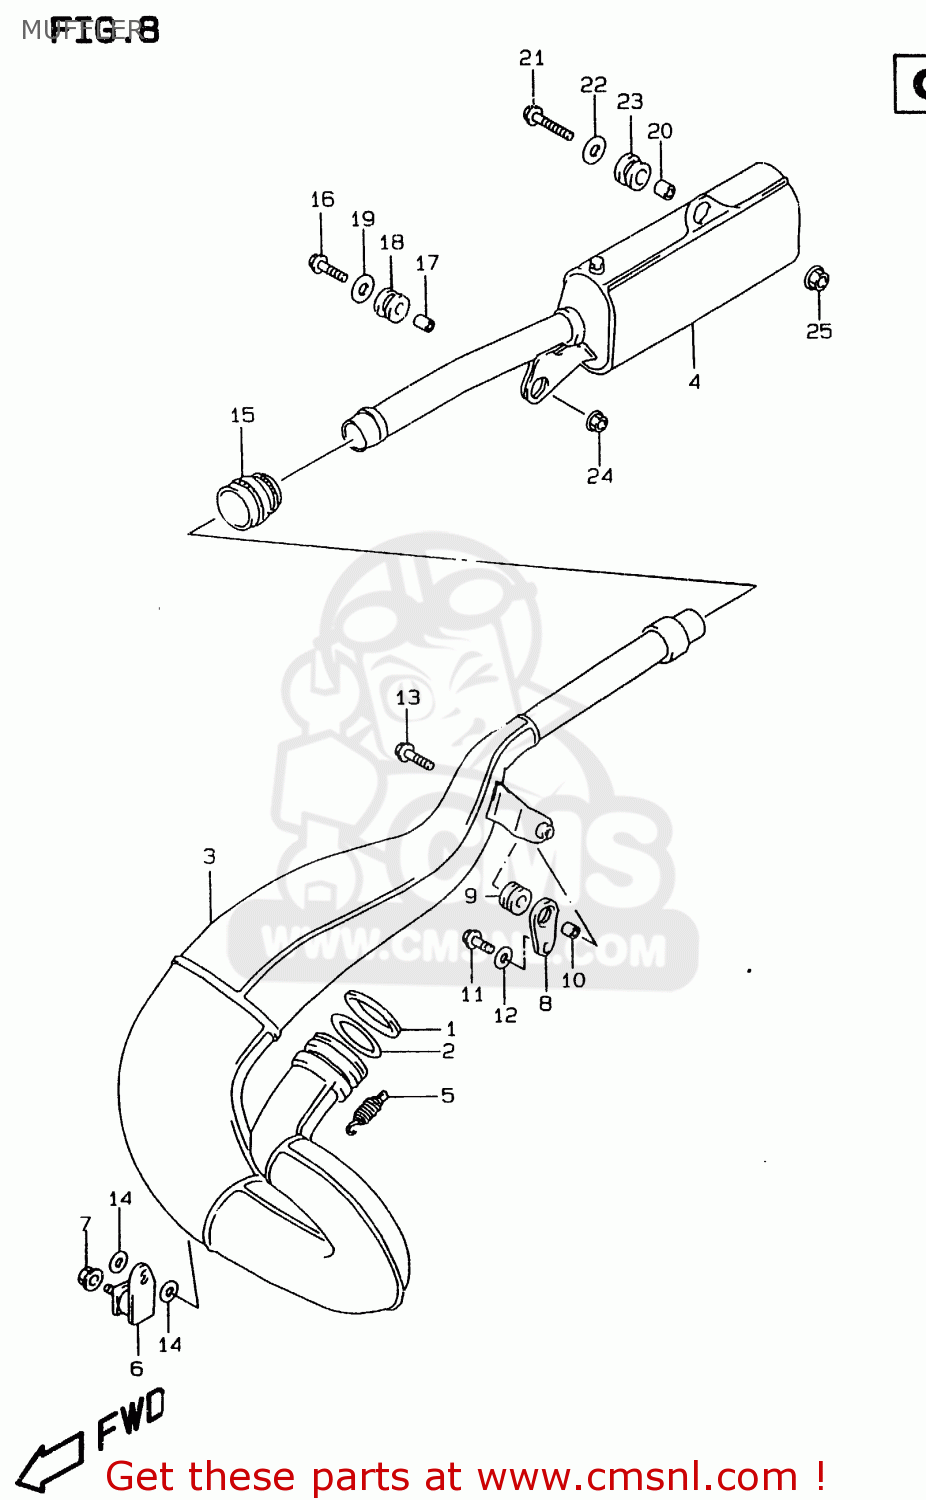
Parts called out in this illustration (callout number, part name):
1	WASHER,EXHAUST PIPE
2	O RING,EXHAUST PIPE
3	BODY,MUFFLER,FIRST
4	MUFFLER, 2ND
5	SPRING
6	DAMPER,MUFFLER SUPPORT
7	NUT
8	PLATE,MUFFLER MTG
9	CUSHION,MUFFLER
10	SPACER(6.5X9X13.5)
11	BOLT
12	WASHER (6.5X20X1.2)
13	SCREW
14	WASHER (8.5X19X2.3)
15	CONNECTOR,MUFFLER
16	SCREW
17	SPACER(6.5X10X9)
18	CUSHION
19	WASHER(6.5X28X1.6)
20	SPACER(8.1X11.5X13)
21	BOLT
22	WASHER(8.5X28X1.6)
23	CUSHION
24	NUT
25	NUT
